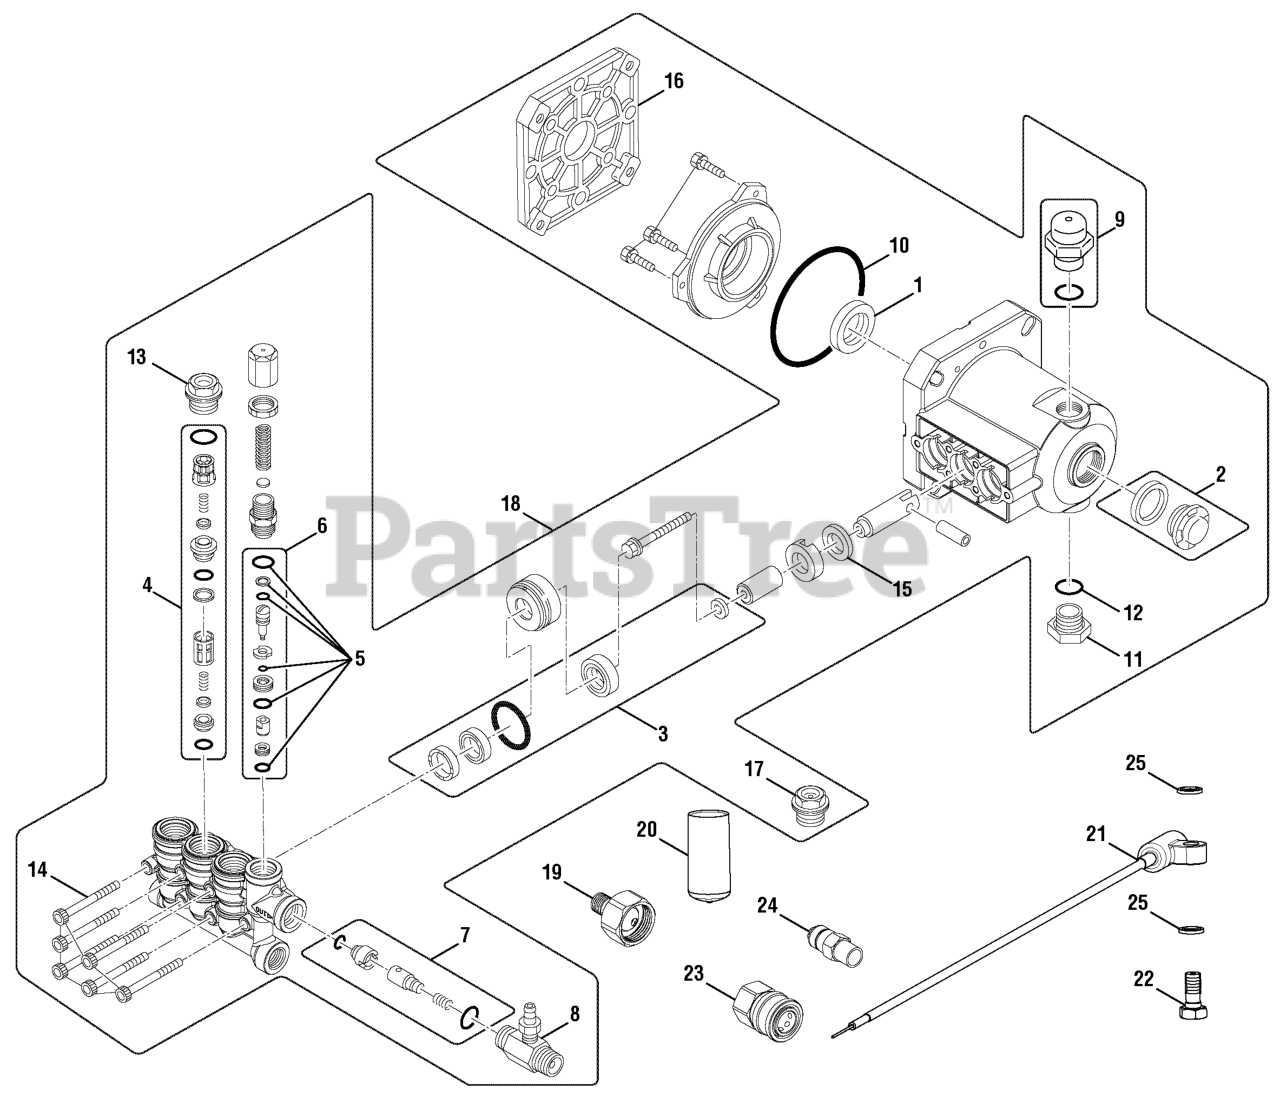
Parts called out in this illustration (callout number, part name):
1	OIL SEAL
3	SEAL KIT
4	VALVE ASSEMBLY
5	O-RING KIT
6	UNLOADER KIT
7	CHECK VALVE KIT
8	FIXED INJECTOR
9	VENT CAP (CAT)
11	DRAIN PLUG
15	OIL SEAL
16	PUMP FLANGE
17	THREADED VALVE PLUG
18	PUMP ASSEMBLY (4GXT30)
19	GARDEN HOSE COUPLER W/FILTER
20	UNLOADER CAP
21	IDLE DOWN ASSEMBLY
22	THROTTLE CONTROL BOLT(SPECIAL)
23	QUICK DISCONNECT (FEMALE)
24	THERMAL RELEASE VALVE
